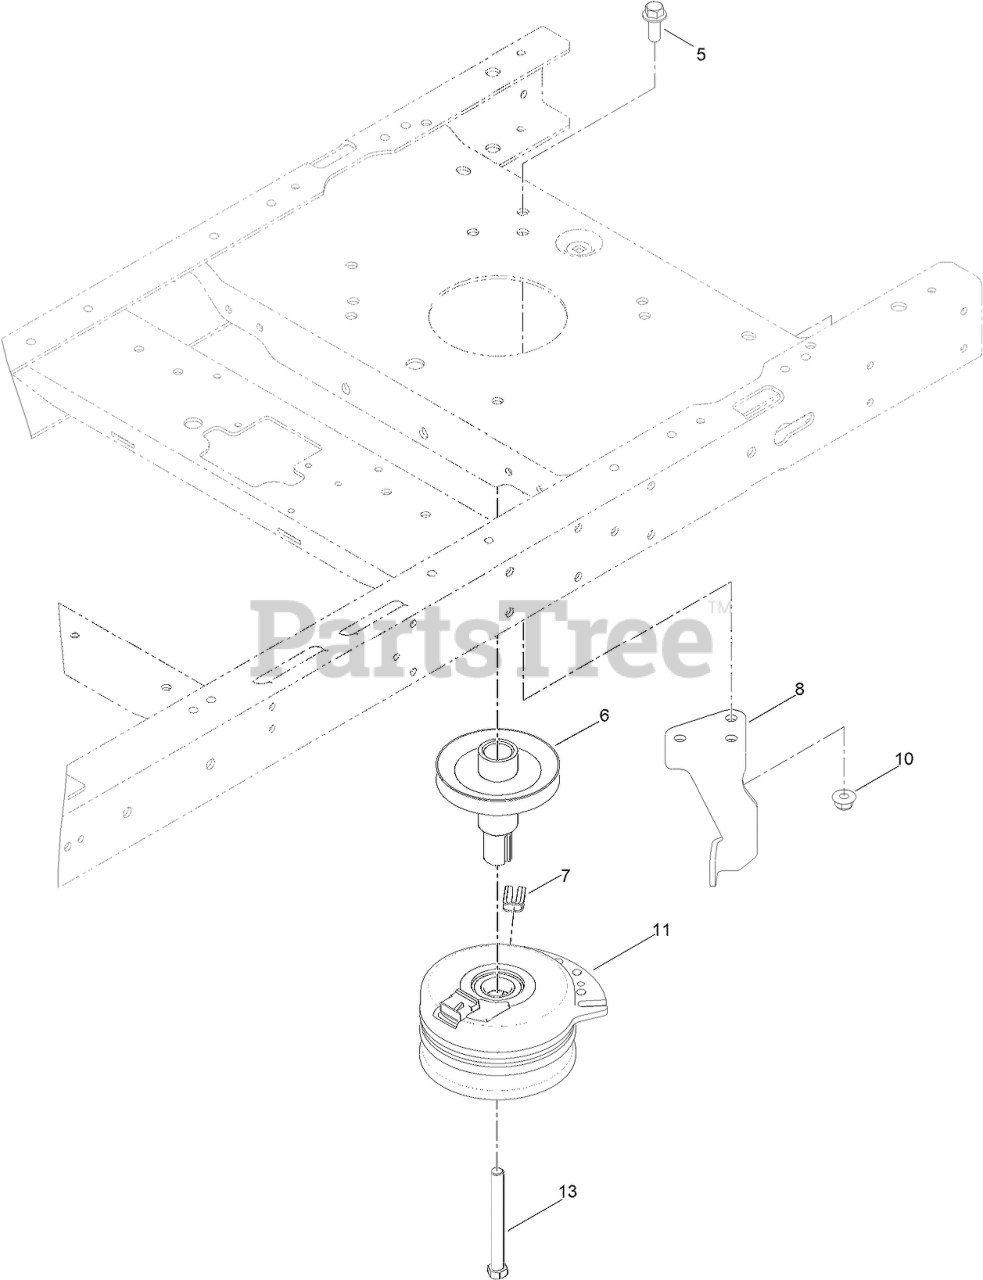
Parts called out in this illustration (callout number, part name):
5	SCREW-HHF
6	PULLEY-ENGINE
7	ISOLATOR-CLUTCH
8	STOP-CLUTCH
10	NUT-HF, NI
11	CLUTCH-ELECTRIC
13	SCREW-HH
